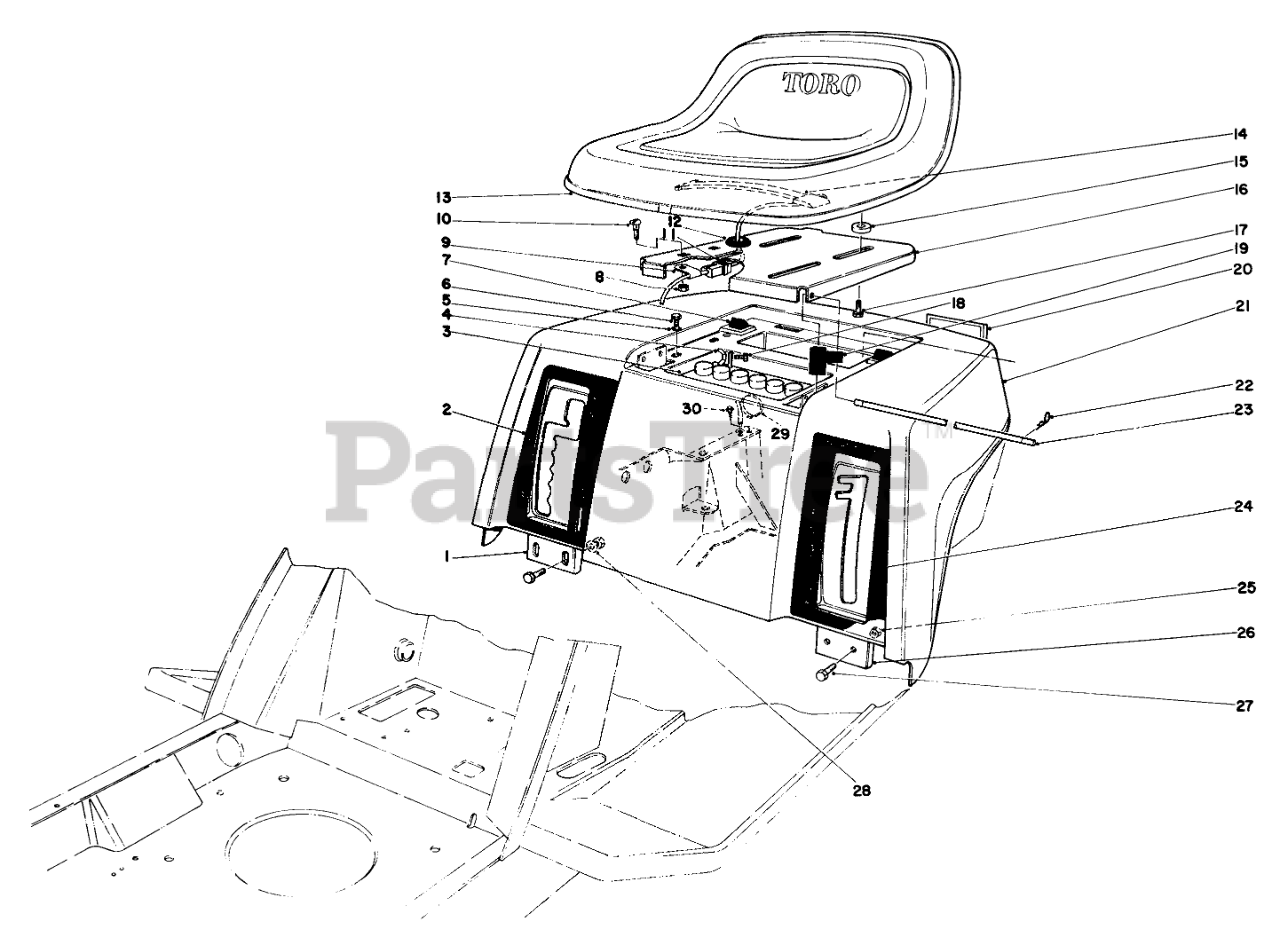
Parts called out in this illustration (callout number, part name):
1	DETENT PLATE B
2	Decal Transmission
3	Battery
4	NUT-WING
5	WASHER
6	SCREW-HWHTF
7	SEAT BUMPER
8	NUT-KEPS
9	CLAMP
10	SCREW-CARR
11	Female Connector
12	GROMMET
14	SWITCH-SEAT
15	SPACER-PIN, MOUNTING
16	SEAT SUPPORT R
17	SCREW-HHF
18	SCREW-HH
19	BOOT-TERMINAL
20	REFLECTOR
21	Rear Body (Incl. Ref. #2 & 24)
22	PIN-COTTER
23	PIVOT-SEAT
24	Decal Height of Cut
25	NUT-LOCK, CONE
26	Quadrant Height of Cut
27	SCREW-HH
28	WASHER-PLAIN
29	TIE-CABLE
30	SCREW-HWHTF
